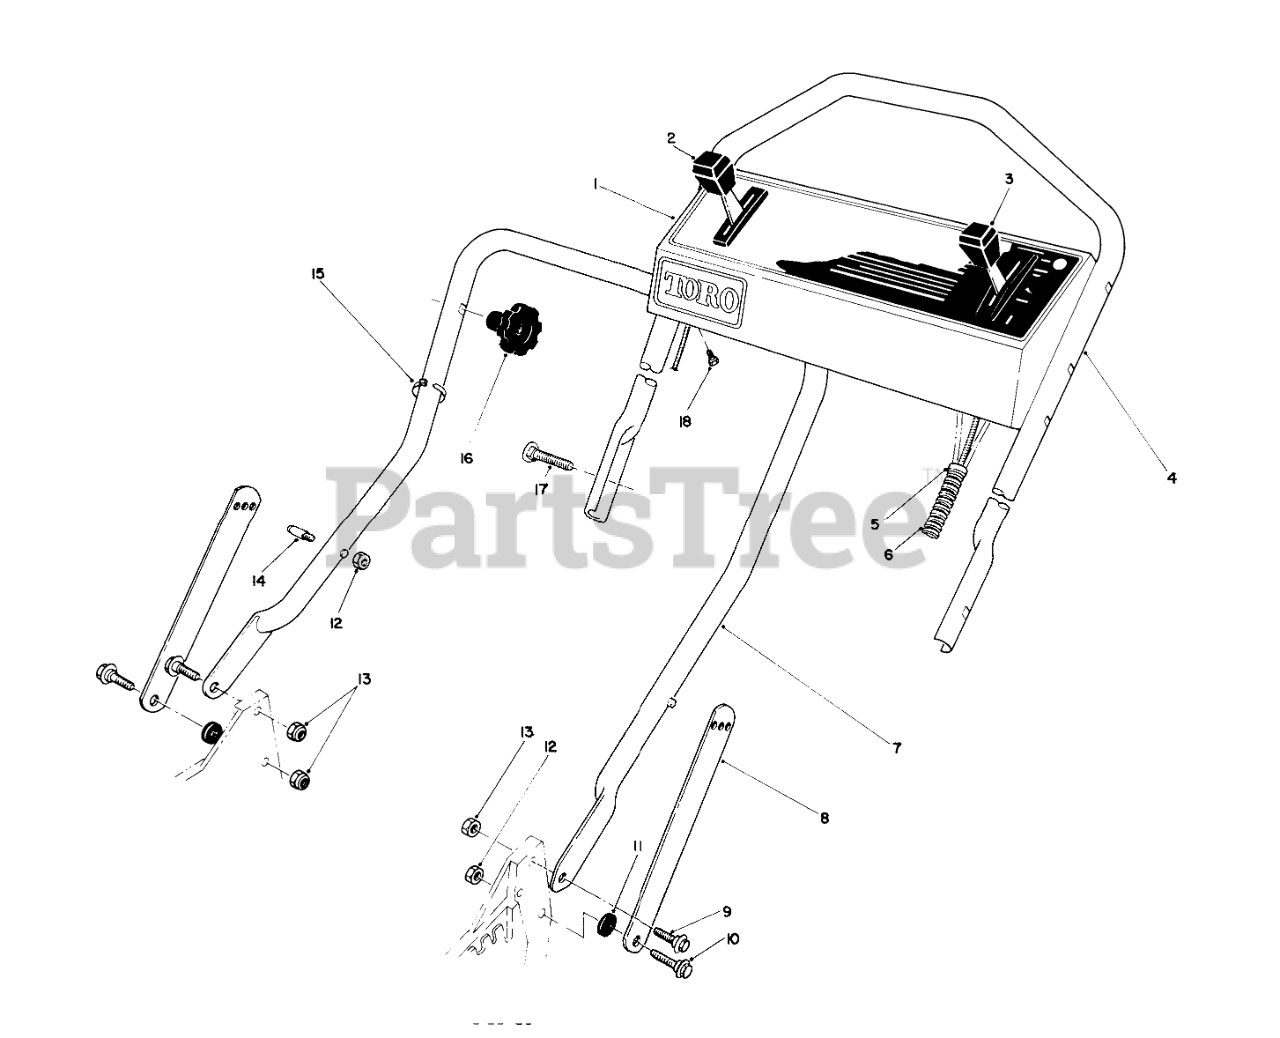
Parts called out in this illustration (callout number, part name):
1	Panel-Control
2	GROUND SPEED CONTROL
3	THROTTLE CONTROL - R&S
4	Handle-Upper
5	FITTING-RING
6	CONTROL CABLE COVER
7	LOWER HANDLE ASM
8	Handle Latch
9	SCREW-SHOULDER
10	SCREW-SHOULDER
11	SPACER
12	NUT-LOCK, NI
13	NUT-LOCK, NI
14	HANDLE PIN
15	TIE-CABLE
17	5/16-18 X 2 HNDLE SCREW
18	SCREW-HWHTF
